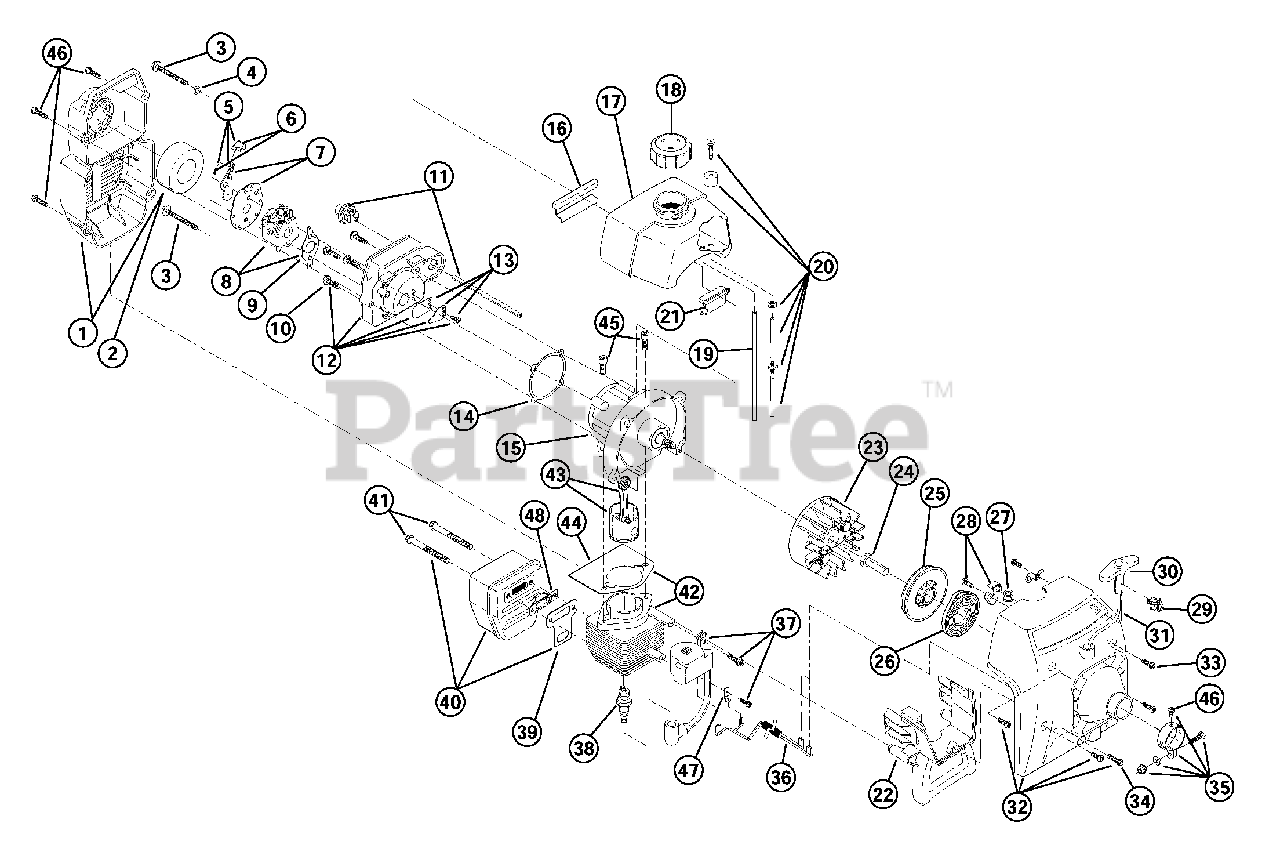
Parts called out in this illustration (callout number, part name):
1	Air Cleaner/Muffler Cover Assembly
2	Air Cleaner Filter
3	Carburetor Mounting Screw Assembly
4	Wavey Washer
5	Choke Lever Assembly
6	Choke Knob and Screw
7	Choke Lever and Plate
8	Carburetor Assembly
9	Carburetor Gasket
10	Carb Mount Screw
11	Primer and Hose Assembly
12	Carb Mount Assembly
13	Reed Assembly
14	Carburetor Mount Gasket
15	Crank Case Service Assembly
16	Rear Mounting Pad
17	Fuel Tank Assembly
18	Fuel Cap Assembly
19	Fuel Return Line
20	Fuel Line Assembly
21	Front Mounting Pad
22	Shroud Extension and Stand
23	Flywheel Assembly
24	Square Nut Drive
25	Recoil Pulley Assembly
26	Recoil Spring
27	Rope Guide
28	Pulley Retainer Assembly
29	Switch Assembly
30	Pull Handle
32	Starter Housing Assembly
33	Housing Screw
34	Cover Screw
35	Upper Clamp Assembly
36	Wire Lead
37	Module Assembly
38	Spark Plug
39	Exhaust Gasket
40	Muffler Assembly
41	Muffler Mounting Bolt Assembly
42	Cylinder Assembly
43	Piston and Rod Assembly
44	Cylinder Gasket
45	Cylinder Bolt
46	Anti-Rotation Screw
47	Ground Tab
48	Spark Arrestor
